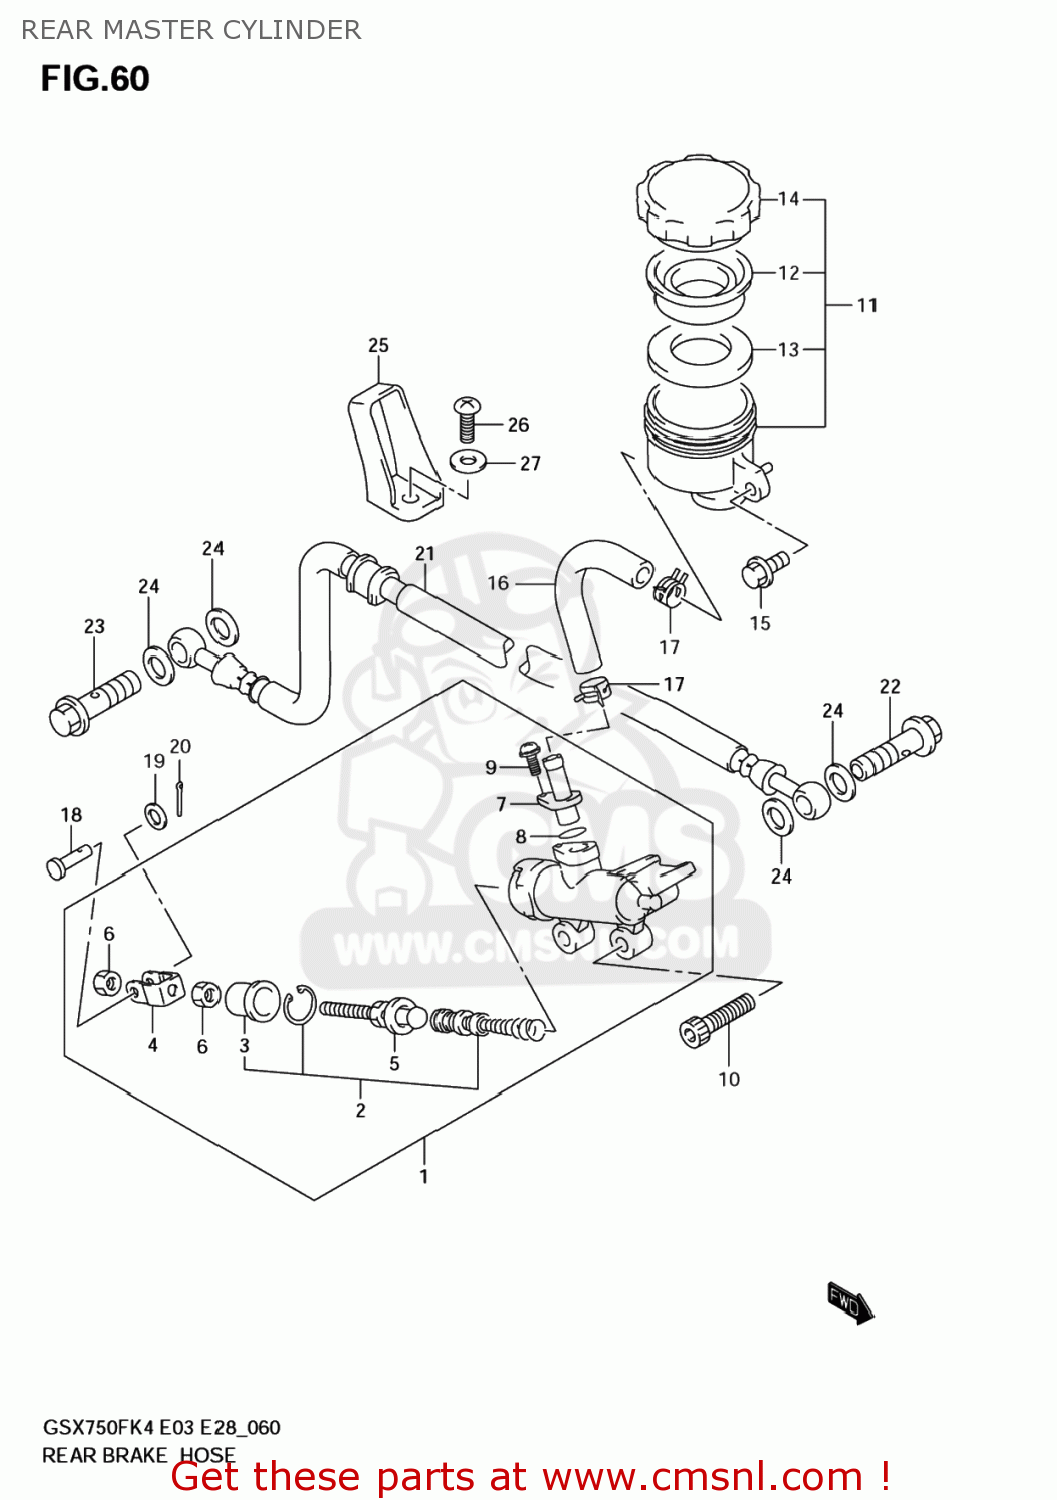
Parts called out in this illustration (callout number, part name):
1	CYLINDER ASSY,RR MASTER
2	PISTON/CUP SET
3	BOOT
4	YOKE
5	ROD,PUSH
6	NUT
7	CONNECTOR
8	O RING
9	SCREW
10	BOLT(6X16)
11	TANK ASSY,RR RESERVOIR
12	DIAPHRAGM
13	PLATE,DIAPHRAGM
14	CAP
15	BOLT
16	HOSE,RESERVOIR TANK
17	CLIP
18	PIN
19	WASHER
20	PIN
21	HOSE COMP,REAR BRAKE
22	BOLT UNION
23	BOLT UNION
24	WASHER(10X15X1.5)
25	GUIDE,RR BRAKE HOSE
26	SCREW
27	WASHER
